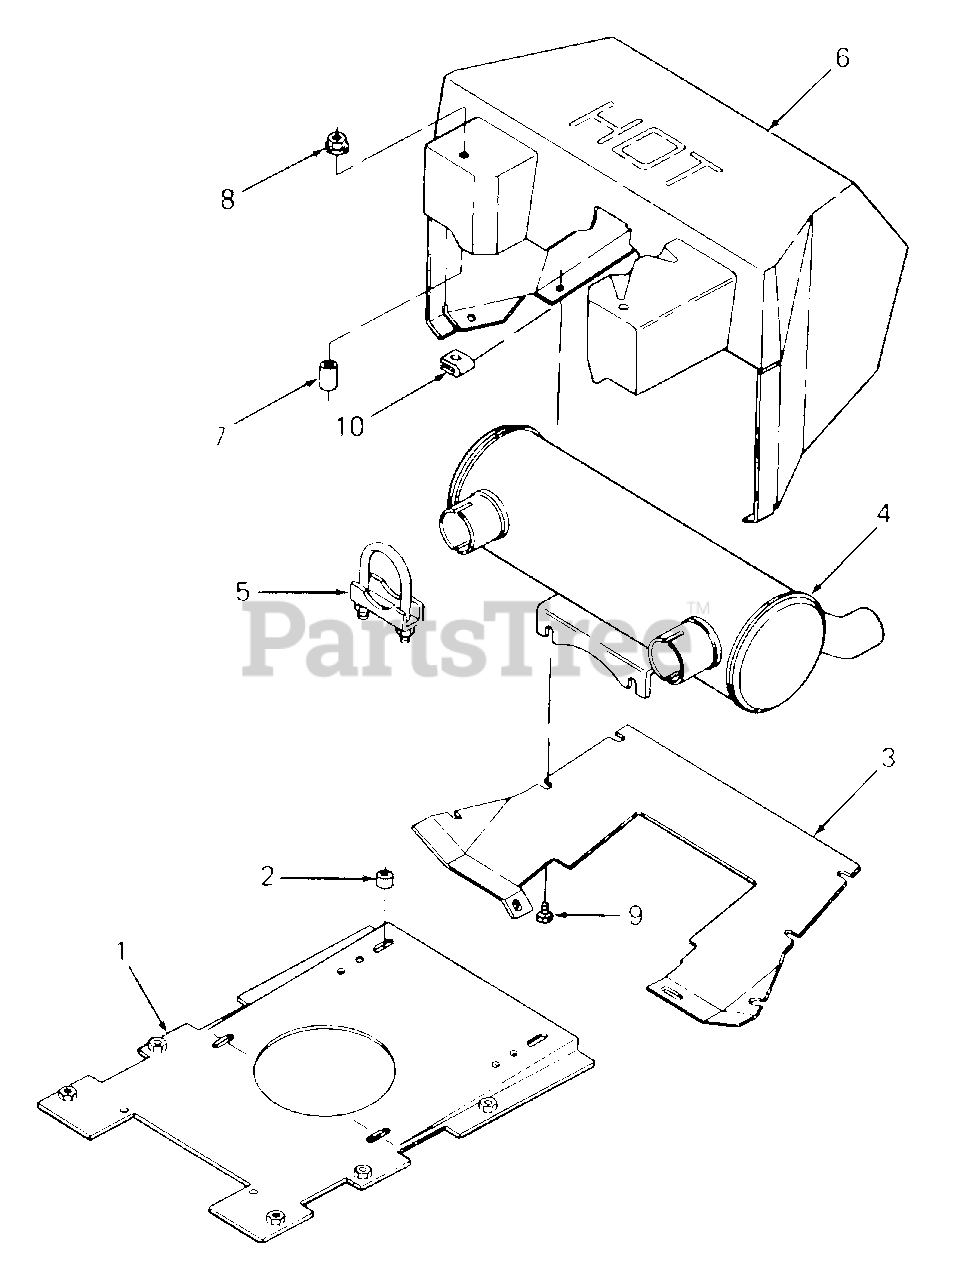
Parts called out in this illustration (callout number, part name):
1	Plate Assy, Engine Mounting
2	Spacer, .423 X .675 X .469 Lg
3	Duct, Bottom Cooling
5	Clamp, Muffler
6	Duct, Top Air
7	Spacer, .326 X .47 X .96 Lg
8	Nut, Hex Flange Lock, 5/16-18
9	Screw, Hex Wash Hd Tapp, 1/4-20 X .50 Lg
10	Nut, U-Type Speed, 1/4-20
